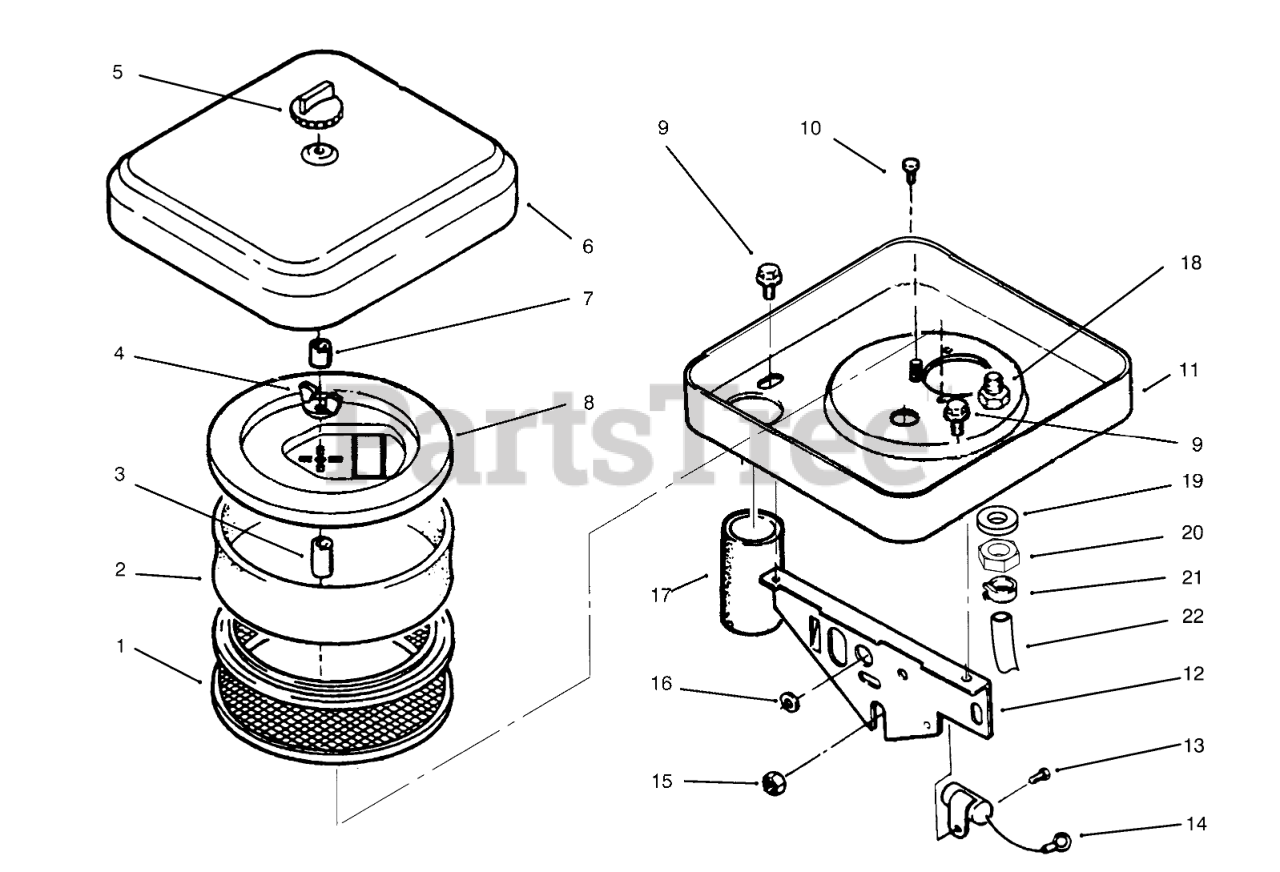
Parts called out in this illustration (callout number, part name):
1	AIR-CLEANER ELEMENT
2	AIR CLEANER ELEMENT
3	SPACER-1" LG
4	1/4-20 WING NUT
6	CHROME-AIR CLEANER
7	SPACER-RUBBER
8	ELEMENT COVER KIT
9	SCREW-TAPPING
10	MACHINE SCREW
11	AIR-CLEANER HOUSING
12	SUPPORT-AIR CLEANER
13	SCREW #10-32 X 5/8
14	CONDENSER
15	WASHER-LOCK
16	GROMMET
17	AIR INTAKE TUBE
18	Fitting-Barbed
19	HOSE FITTING GASKET
20	TAPPET NUT
21	CLAMP-HOSE
